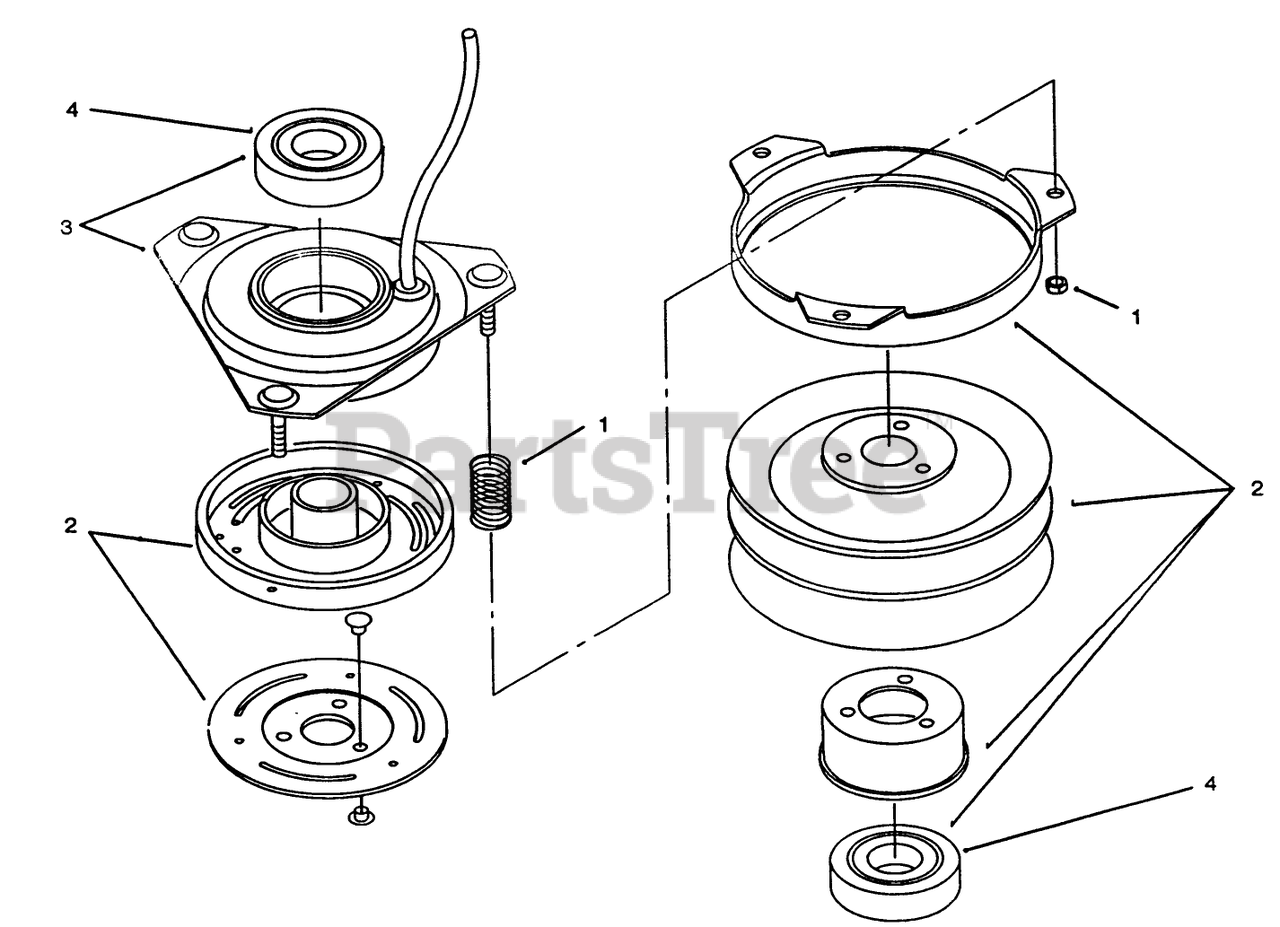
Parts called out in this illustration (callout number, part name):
1	ACCESSORY PKG SRVC PART
2	ROTOR & ARMATURE ASSY
3	FIELD ASSY (SRVC PART)
4	BEARING-ELEC CLUTCH
